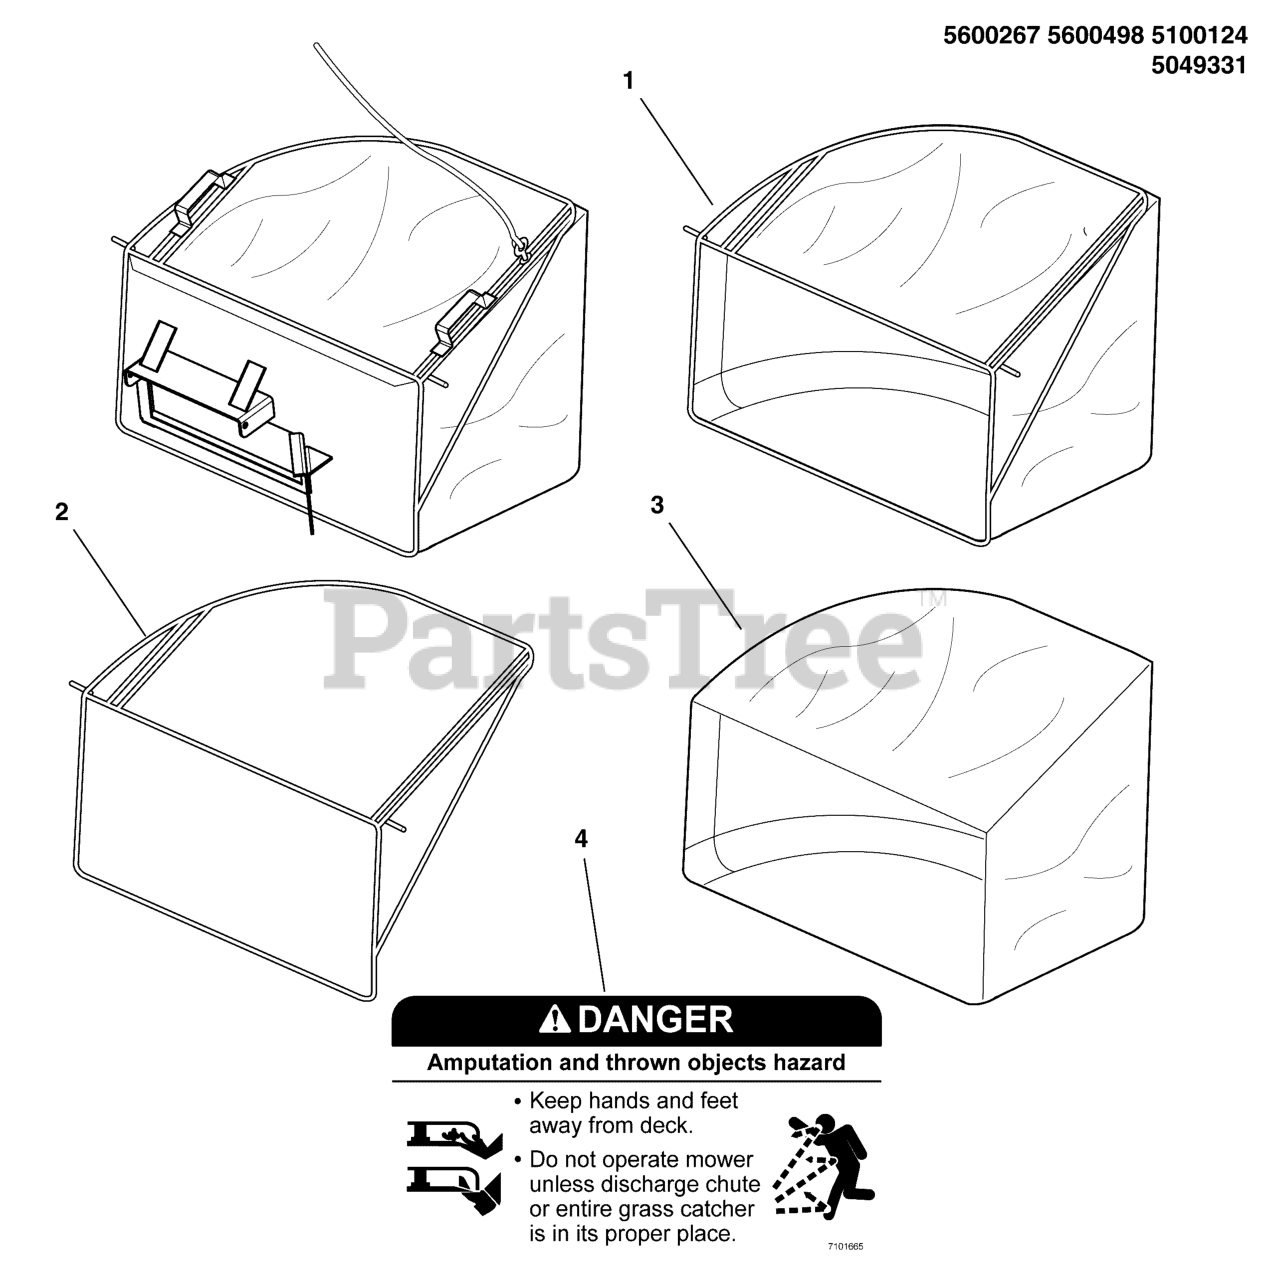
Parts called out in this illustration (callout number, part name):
1	COLLECTION BAG ASM, 3.75 BUSHEL - NET
2	SIDE CATCHER FRAME DUAL PURP.- FRA150000
3	3.75 BUSHEL BAG - 305 001 213
4	DECAL, DANGER DO NOT OPERATE W/O DEFLECT
